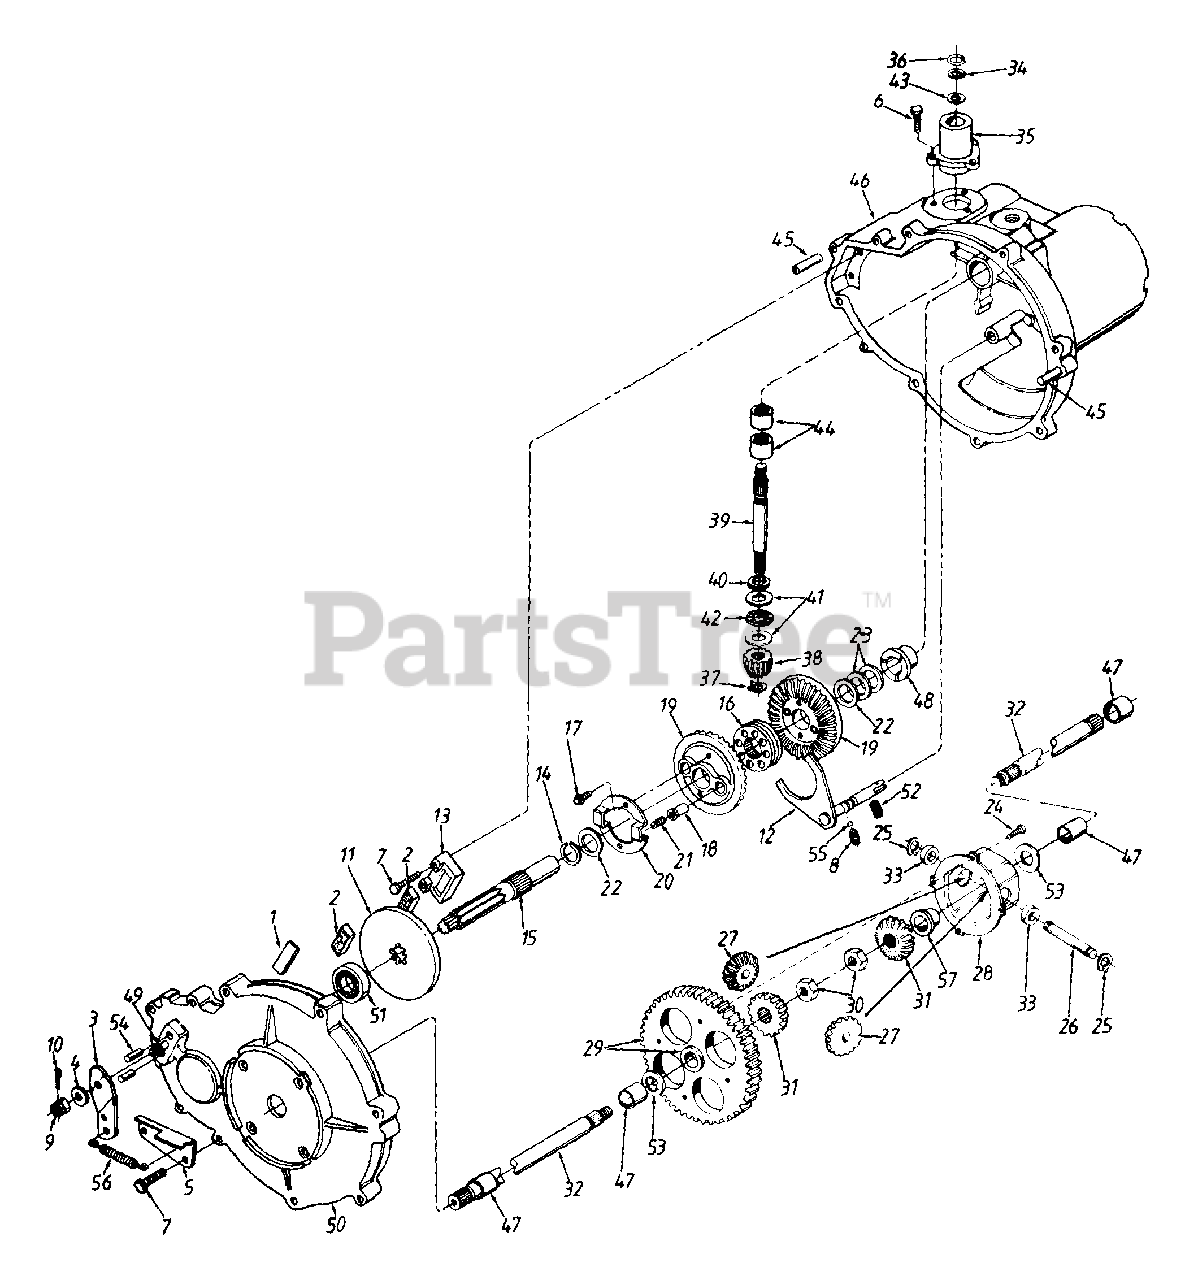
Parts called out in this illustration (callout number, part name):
1	Puck Plate
2	Brake Puck
3	Actuating Arm
4	Fl-Wash. 11/32" I.D. x 7/8" O.D.
5	Brake Stop Brkt.
6	Hex Bolt 1/4-20 x .62" Lg.
7	Hex Tap Scr. 1/4-20 x 1.25" Lg.
8	Spring Detent
9	Castle Nut 5/16-24 Thd.
10	Cotter Pin 3 32" Dia. x 1" Lg.
11	Brake Disc
12	Shifter Ass'y.
13	Brake Puck Holder
14	Retaining Ring
15	Shaft Drive
16	Shift Collar
17	Hex Wash. Hd. Tap Scr. 1/4-20 x .38" Lg.
18	Drive Pin
19	Bevel Gear Ass'y.
20	Spring Retaining Plate
21	Drive Spring
22	Fl-Wash..915" I.D. x 1.5" O.D.
23	Fl-Wash..915" I.D. x 1.37" O.D.
24	Pan Hd. Scr. 1/4-20 x .5" Lg.
25	Snap Ring
26	Cross Shaft
27	Miter Gear 15T
28	Differential Can Assembly
29	Differential Gear Ass'y. w/Bearing
30	Hex Ins. L-Nut 1/2-20 Thd.
31	Miter Gear
32	Axle
33	Differential Thrust Spacer
34	Retainer Ring
35	Input Bearing Housing
36	Wire Ring
37	Retaining Ring
38	Pinion Input 14T
39	Input Shaft
40	Seal 5/8" I.D.
41	Thrust Wash..621" I.D. x 1.12"
42	Thrust Bearing
43	Fl-Wash. 5/8" I.D. x 1.0" O.D.
44	Needle Brg. 5/8" x 1/2" Lg.
45	Dowel Pin
46	R.H. Housing
47	Sleeve Bearing 3/4" I.D.
48	Flange Bearing .906" I.D.
49	Sq. Head Bolt 5/16-24 Thd.
50	L.H. Housing
51	Ball Bearing .669" I.D.
52	Set Screw 5/16-18 x 3/8" Lg.
53	Fl-Wash..76" I.D. x 1.5" O.D.
54	Brake Actuating Pin
55	Ball Detent
56	Ext. Spring 1.14" Lg.
57	Differential Flange Brg.
